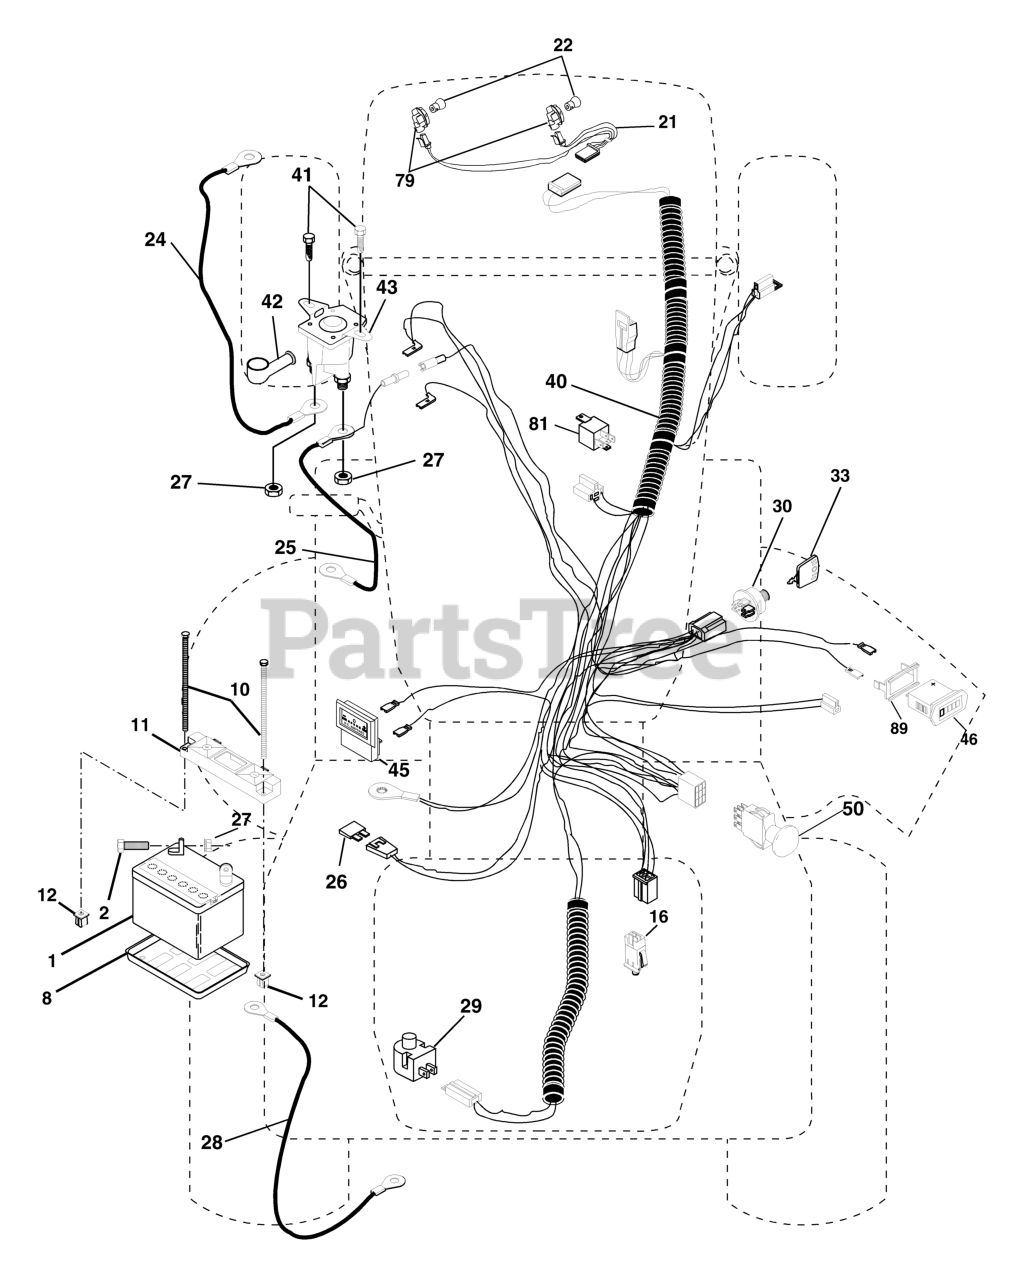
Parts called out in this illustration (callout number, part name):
1	BATTERY 12V .35 AMP
2	BOLT.HEX.1/4.X.3/4.DICHROMATE
8	BATTERY TRAY T
10	BOLT 1/4-20 X 7.5
11	BATTERY HOLDDOWN FRONT MOUNT
12	NUT, PUSH NYLON 1/4" BATTERY
16	SWITCH INTERLOOK PUSH-IN
21	HARNESS.W/LIGHT SOCKET
24	CABLE-BATTERY YTV
25	CABLE, BATTERY
27	NUT
28	CABLE, GROUND
29	PLUNGER SWITCH (COLOR:OLIVE)
30	IGNITION SWITCH
33	KEY MLD GEN DELTA
40	HARNESS, IGNITION
41	SCREW
42	TERMINAL COVER
43	SOLENOID
46	HOUR METER
50	RP.PTO.SWITCH.8 TERMINAL.BLACK
79	BULB HOLDER ASM.
81	RELAY.ASSY.T
89	BRACKET SNAP-IN HOURMETER
